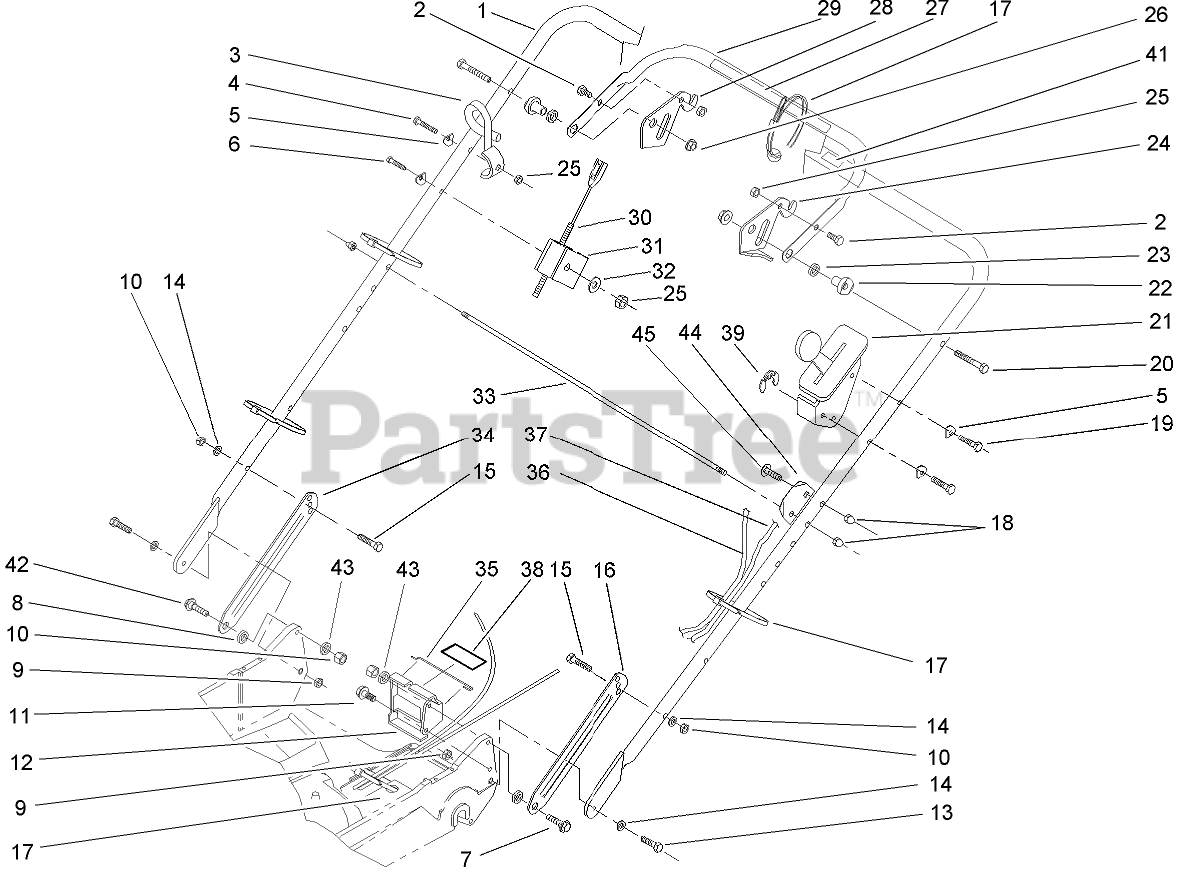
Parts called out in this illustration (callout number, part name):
2	SCREW-HH
3	GUIDE-ROPE
4	SCREW-HH
5	WASHER
6	SCREW-HH
7	SCREW-SHOULDER
8	SPACER
9	NUT-LOCK, NI
10	NUT-LOCK, NI
11	SCREW-HWHTF
12	BRACKET-ADJUSTMENT, TRACTION
13	SCREW-HH
14	WASHER-BELLEVILLE
15	SCREW-HH
16	LATCH-HANDLE, LH
17	TIE-CABLE
18	NUT-CAP
19	SCREW-HH
20	SCREW-HH
21	CONTROL-THROTTLE
22	SPACER-SUPPORT
23	SPACER-NYLON
24	LEVER-CONTROL
25	NUT-LOCK, NI
26	NUT-LOCK, NI
27	Decal-Traction
28	LEVER-CONTROL
29	BAR-CONTROL
30	CABLE-BRAKE
31	SUPPORT-CABLE
32	WASHER-FLAT
33	ROD-SUPPORT, BAG
34	LATCH-HANDLE, RH
35	RETAINER-CABLE
36	CABLE-TRACTION
37	THROTTLE CABLE ASM
38	DECAL-POSITION, GEAR
39	E-RING
41	DECAL-PROTECTION, EAR
42	SCREW-SHOULDER
43	WASHER-PLAIN
44	PLATE-ALIGNING, BAG
45	SCREW-CARR
